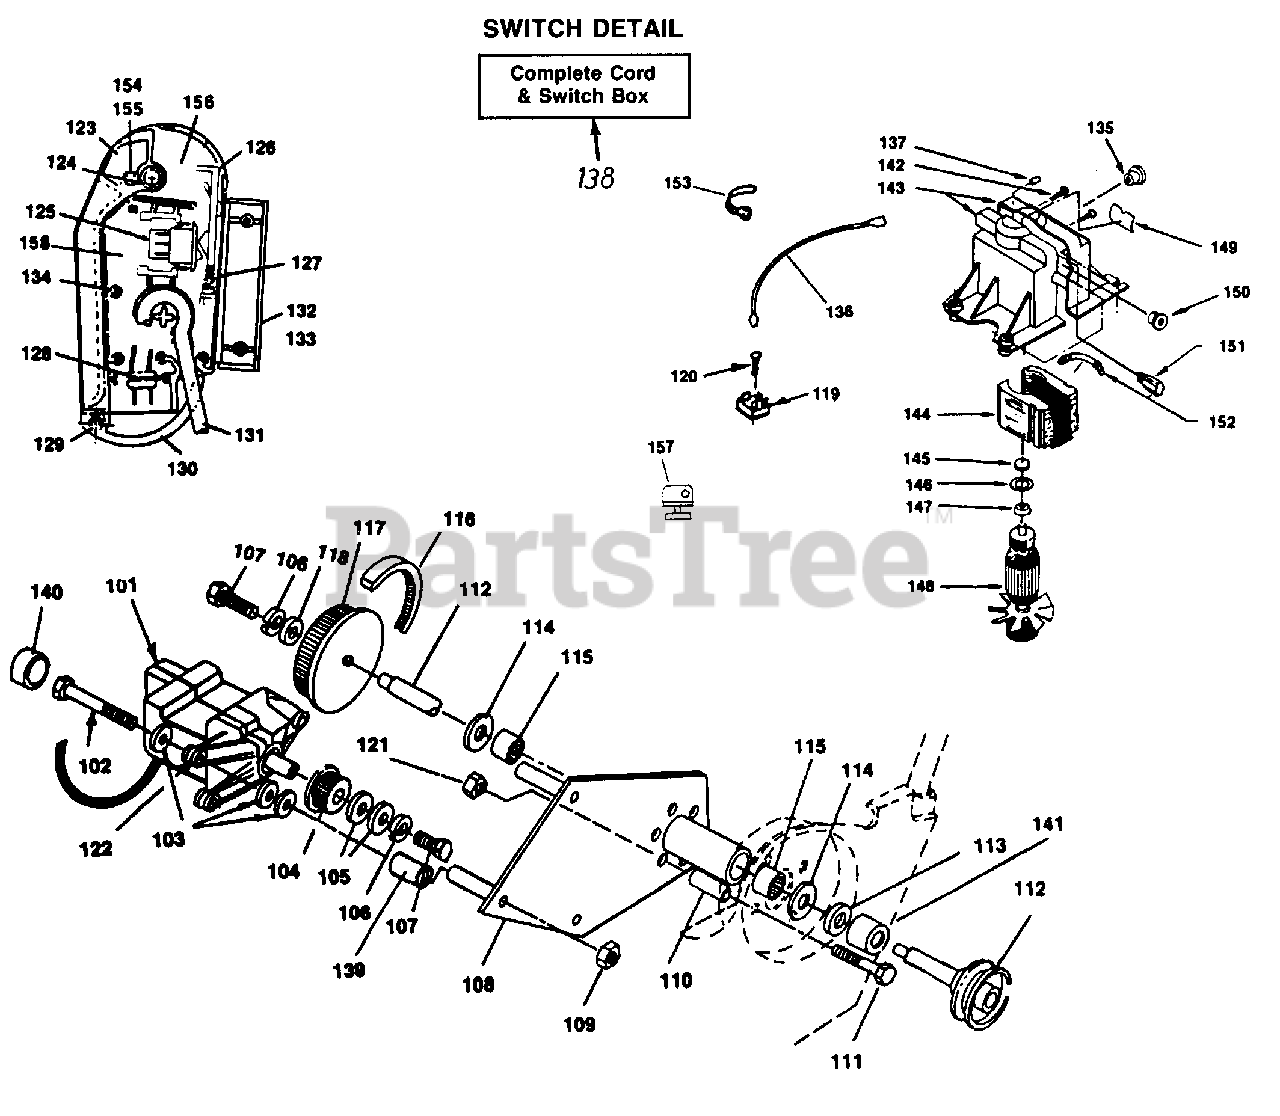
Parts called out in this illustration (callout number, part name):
101	Motor and Switch Box Ass'y.
102	Hex Bolt 1/4-20 x 3-1/4" Grade 5 Special
103	Washer 1/4"
104	Pulley-Motor
105	Washer
106	L-Wash. 1/4n I.D.
107	Hex Bolt 1/4-20 x 3/4"" Grade 5 Special
108	Plate Assembly
109	Lock Nut 1/420 Thd.
110	Spacer
111	Hex Bolt 5/16-18 x 1-1/2"
113	Washer
114	Washer-Thrust
115	Bearing-Needle
116	Belt-Cog
117	Pulley-Shaft
118	Washer-Special
119	Rectifier
120	Tap Scr. #10-24 x 3/4"
121	Lock Nut 5/16-24 x 3/4"
122	Insulator-Motor Housing
123	Handle Dash Switch Actuator
124	Spring-Switch Handle
125	Switch
126	Latch
127	Spring-Latch
128	Plug-2 Prong
129	Spring-Cord Retainer
130	Cord Retainer
131	Cord Assembly
132	Housing-Upper Half
133	Housing-Lower Half
135	Bushing-Split
136	Jumper Wire Assembly (Blue)
137	Pad-Pressure
138	Cord & Switch Box Ass'y. Complete
139	Spacer Insulator
140	End Cap Insulator
141	Spacer
142	Screw-Motor Housing
143	Kit-Motor Housing (Both Halves)
144	Field Assembly
145	Oil Wick
146	"O"-Ring
147	Bearing-Spherical
148	Armature & Pulley Ass'y.
149	Spring-Field
150	Strain Relief
151	Brush Assembly
152	Wire Clip
153	Plastic Tie
154	Pin-Handle Lock
155	Spring-Handle Lock Pin
156	Plate-Key
157	Key-Switch Box
